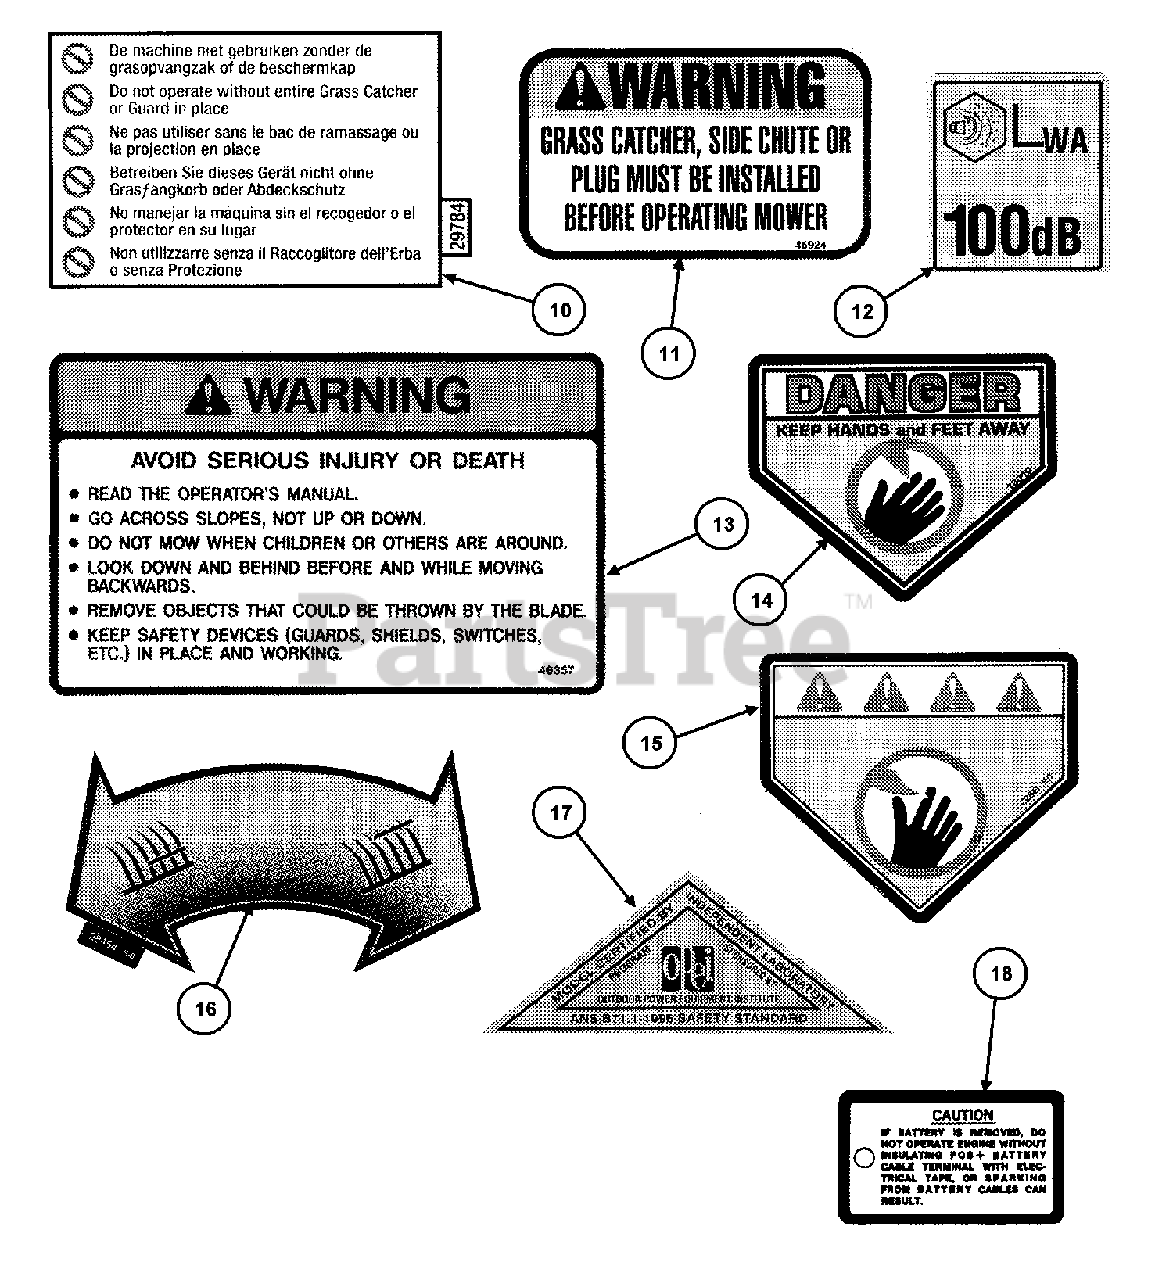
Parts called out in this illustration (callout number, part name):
10	DECAL, Chute/International Warning
11	DECAL, Chute Deflector
12	DECAL, Noise
13	DECAL, Warning 1997
14	DECAL, Danger (Keep Hands and Feet Away)
15	DECAL, Warning (International Symbol)
16	DECAL, Height Control Instruction (Euro)
17	DECAL, OPEI, OPEI Ride-On
18	DECAL, Caution Tag
